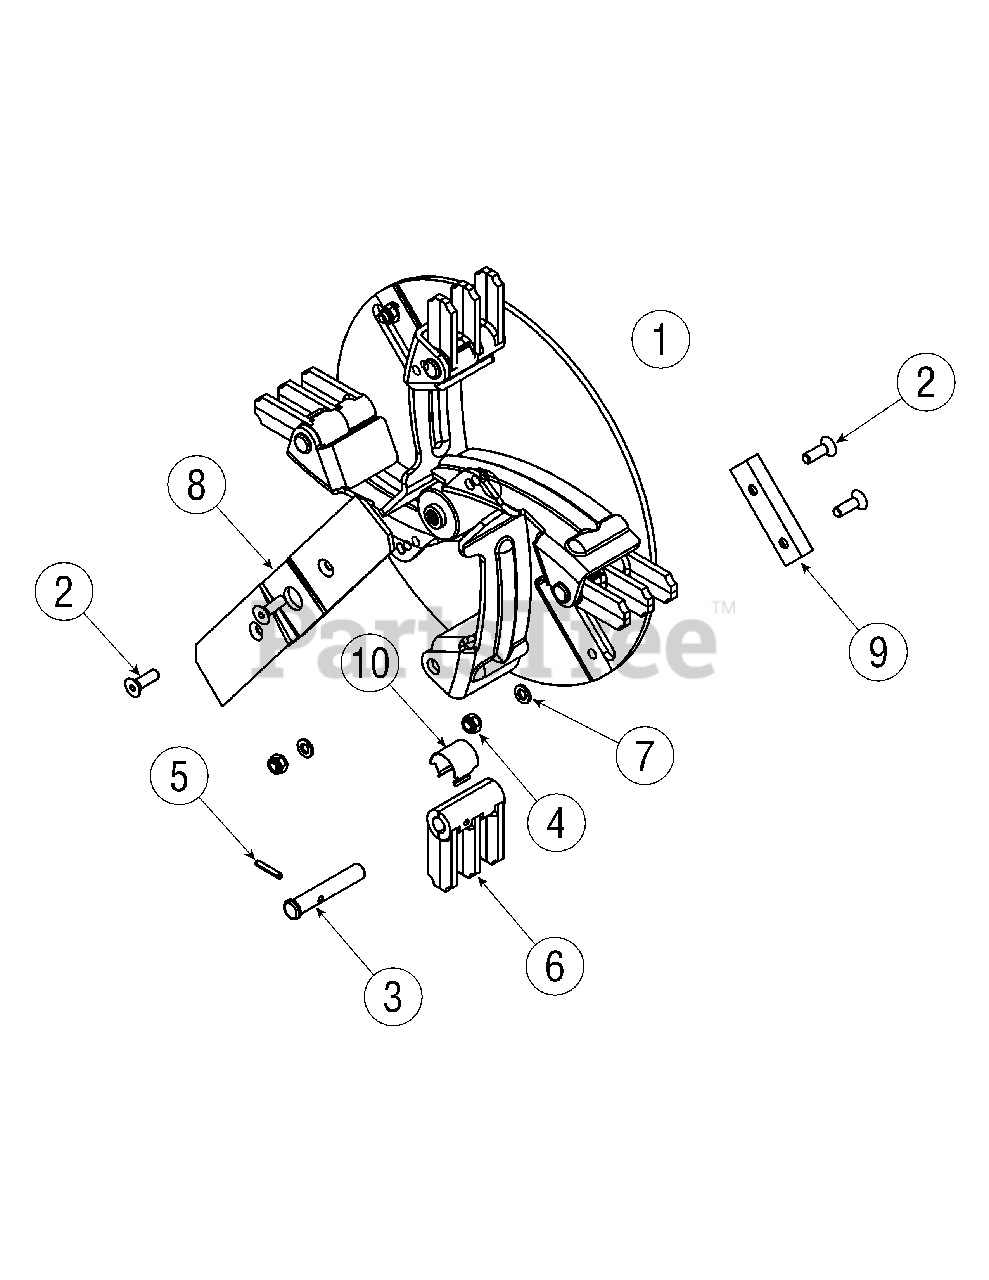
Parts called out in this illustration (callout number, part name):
1	Impeller Assembly Complete
2	Machine Screw, 5/16-24 x 1.0
3	Clevis Pin,.496
4	Hex Lock Nut, 5/16-24
5	Spiral Pin,.156 x 1.0
6	Flail
7	Lock Washer, 5/16
8	Shredder Blade
9	Chipper Blade
10	Retainer Clip
